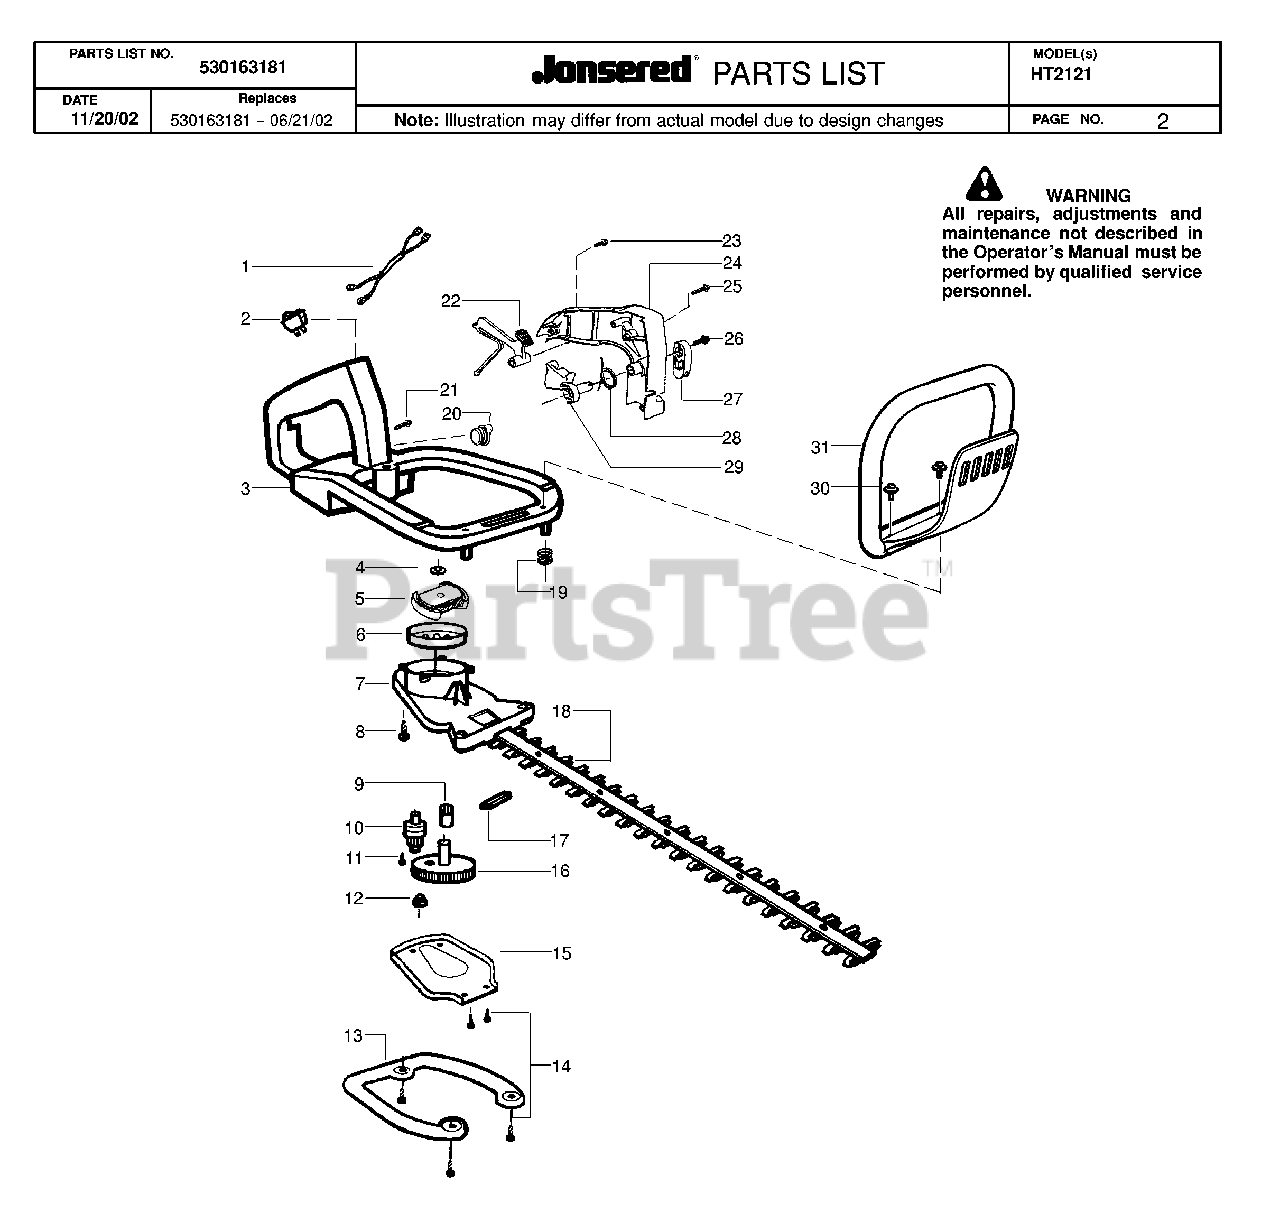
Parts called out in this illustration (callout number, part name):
3	ASSY-REAR HANDLE & TANK
4	WASHER FLAT
6	CLUTCH DRUM
7	GEARBOX ASSY
8	SCREW-10-14 X 13/16 (PL
11	SCREW-10-16 X 1/2, TYPE 2
12	BLADE BUSHING
13	ISOLATOR PLATE
15	PLATE-GEARBOX COVER
18	BLADE ASSEMBLY
19	ANTIVIBE MOUNT
20	COVER
21	SCREW-10-16 X 1-3/8 PLA
22	LOCKOUT-THROTTLE
26	SCREW 8-16 X 9/16 (PLAS
